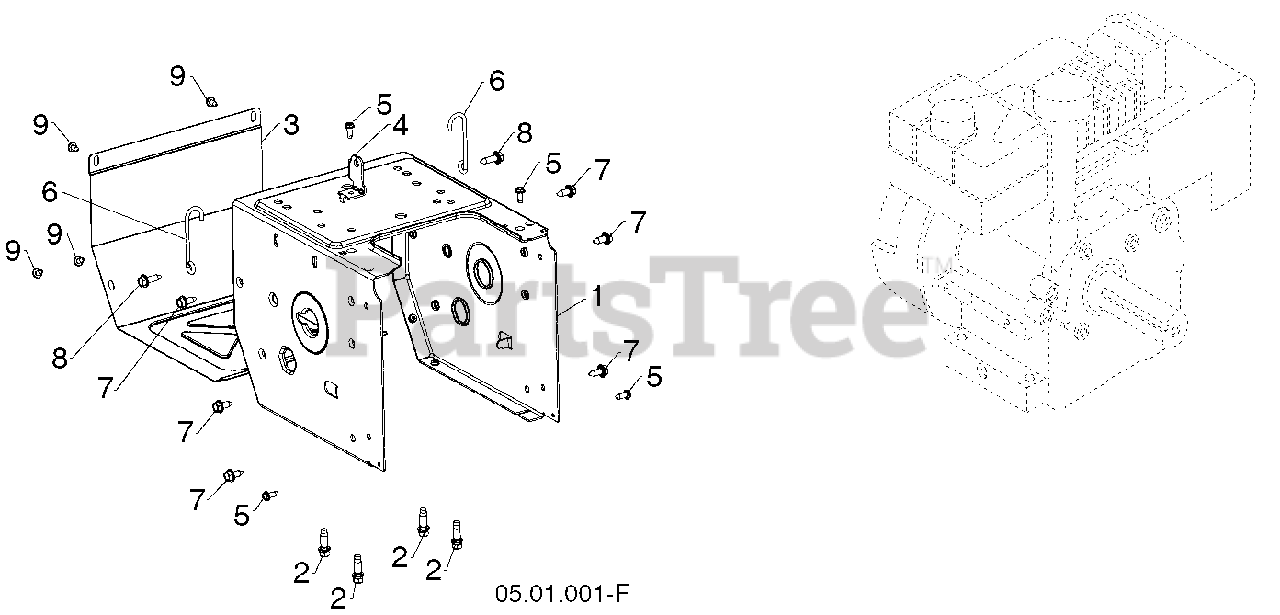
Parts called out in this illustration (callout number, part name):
1	FRAME.GEAR.CASE.ORANGE
2	BOLT 3/8-16X1-1/8
3	COVER COVER.FRAME MS668 ORANGE
4	BRACKET.SHIFTER.BZP
5	SCREW 14-20 X 5/8
6	WIREFORM.SUPPORT.CABLE
7	BOLT.HEX.HD.WASHER.5/16-18X.75
8	SCREW HEX_SERR_HD_5_16-18X1.0
